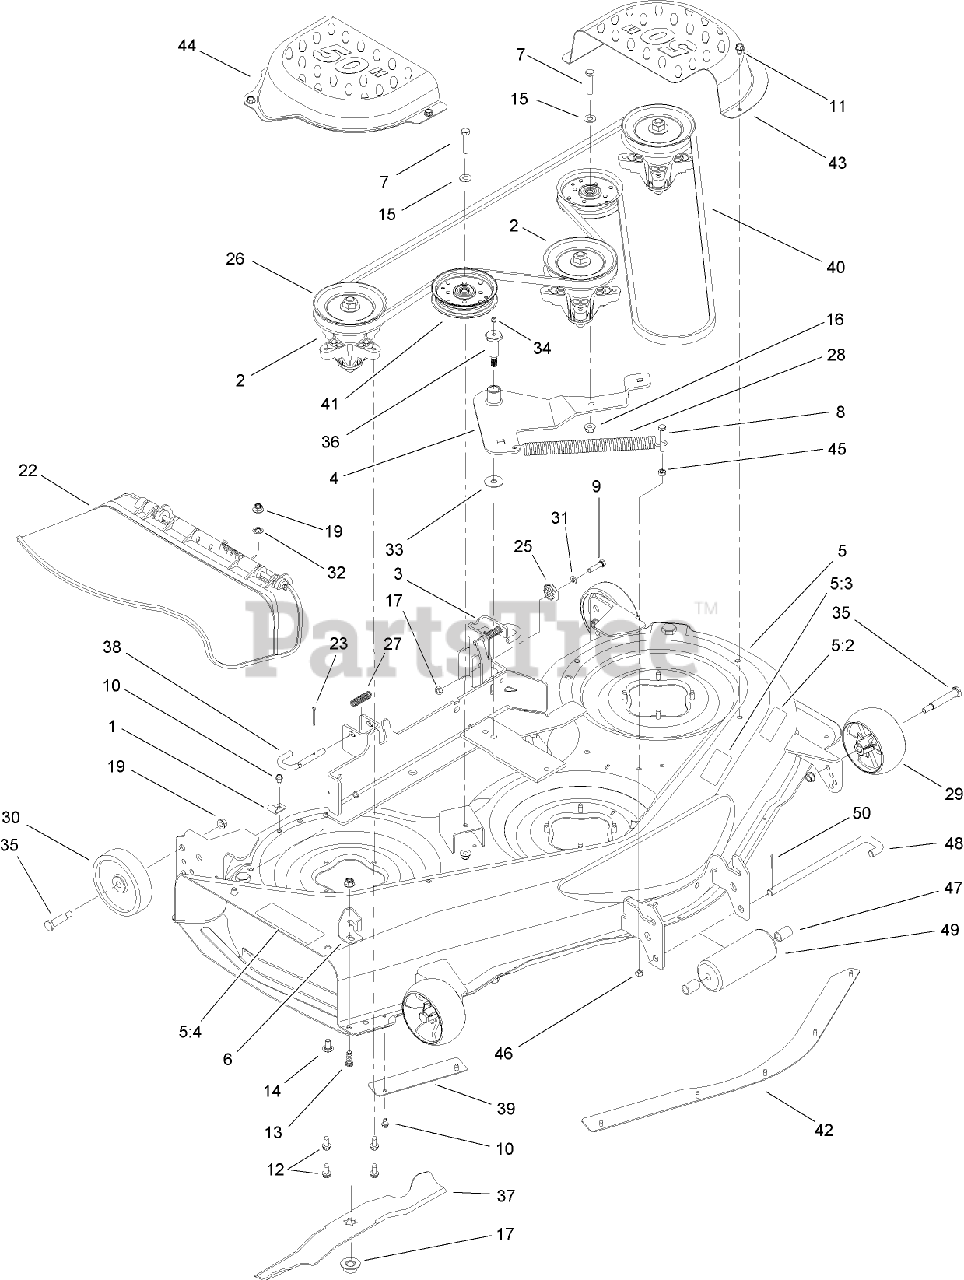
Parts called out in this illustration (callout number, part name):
1	BRACKET-RETAIN, HOOK
2	SPINDLE ASM
3	LH HANGER BRACKET ASM
5	DECK AND DECAL ASM
5:3	DECAL-BELT ROUTING, DECK
5:4	DECAL-DANGER
6	STOP-CHUTE
7	SCREW-HH
8	SCREW-HH
9	SCREW-HH
10	SCREW-HWHTF
11	SCREW-HH, TAP
12	SCREW-HWH
13	SCREW-HH
14	BOLT-CARR
15	WASHER-FLAT
16	NUT-LOCK, FLANGE
17	NUT-LOCK, FLANGE
19	NUT-LOCK, FLANGE
22	CHUTE ASM
23	PIN-COTTER
25	GEAR-ADJUSTMENT, DECK
26	PULLEY-DECK
27	SPRING-COMPRESSION
28	SPRING
29	WHEEL-DECK, FRONT
30	WHEEL-DECK, REAR
31	WASHER-LOCK
32	RETAINER-BOLT
33	WASHER-FLAT
34	FITTING-GREASE
35	BOLT-SHOULDER
37	BLADE-17.90 INCH
38	PIN-HANDLE, DECK RELEASE
39	SKIRT-RH
40	BELT-V, TYPE B
41	PULLEY-IDLER
42	SKIRT-CENTER
43	COVER-BELT, LH
44	COVER-BELT, RH
45	NUT-HEX
46	NUT-LOCK, FLANGE
47	SPACER
50	PIN-COTTER
